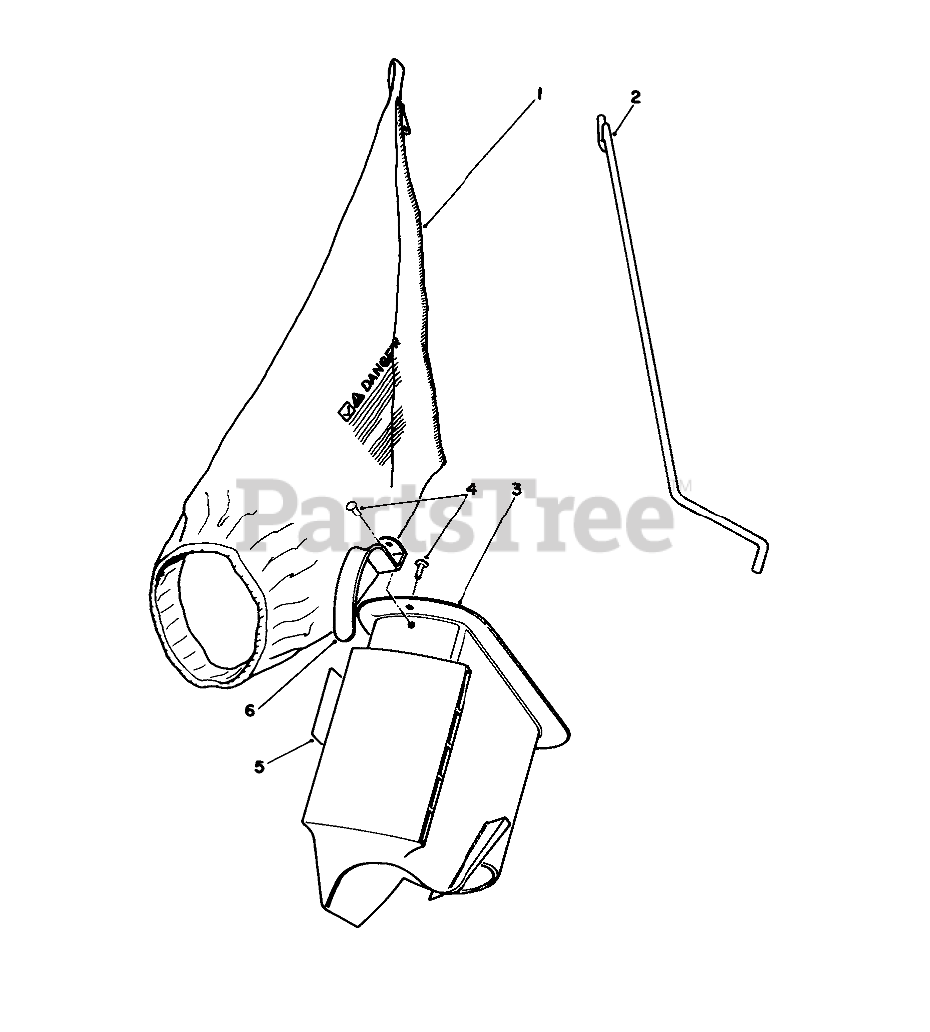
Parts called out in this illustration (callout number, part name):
1	Grass Bag
2	BAG ROD
3	Grass Chute (Incl. Ref. #4 & 6)
4	RIVET 3/16 X 7/16
5	BAG CHUTE DECAL
6	HANDLE-GRASS CHUTE
